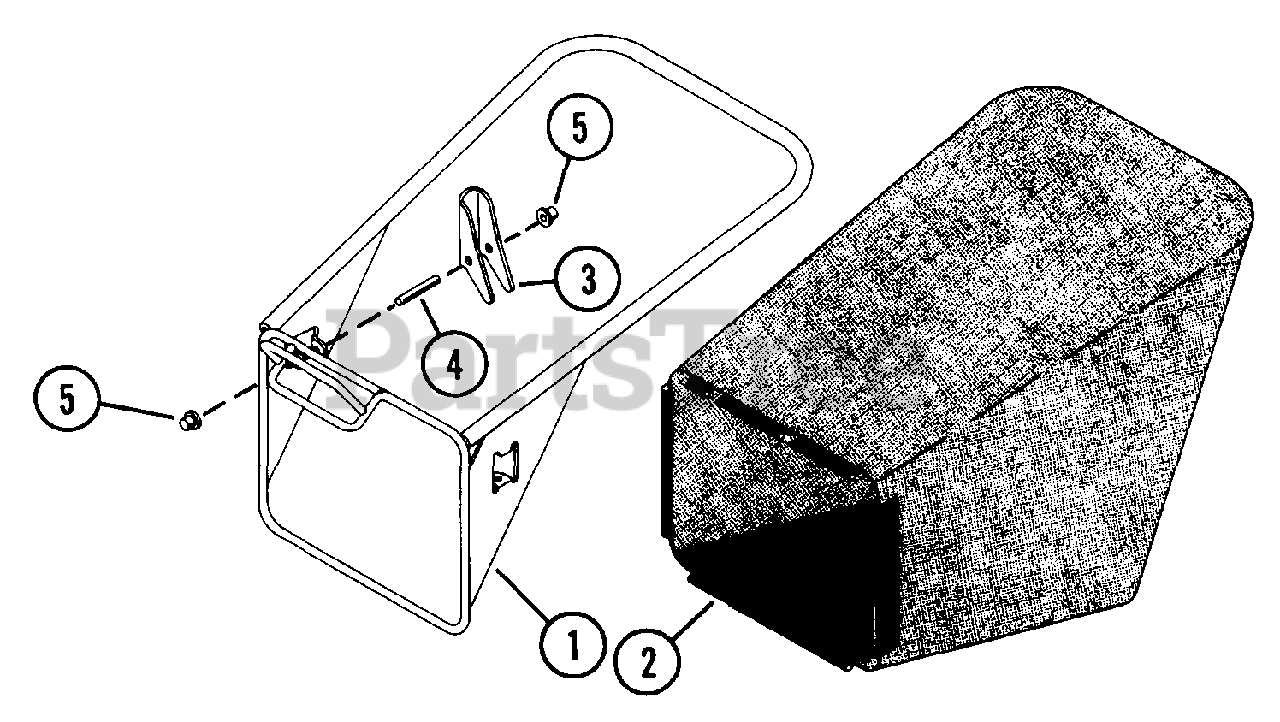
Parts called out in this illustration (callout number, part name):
1	CATCHER FRAME
2	GRASS CATCHER BAG
3	DISCHARGE DOOR RETAINER
4	HINGE PIN
5	PUSH NUT, .188
